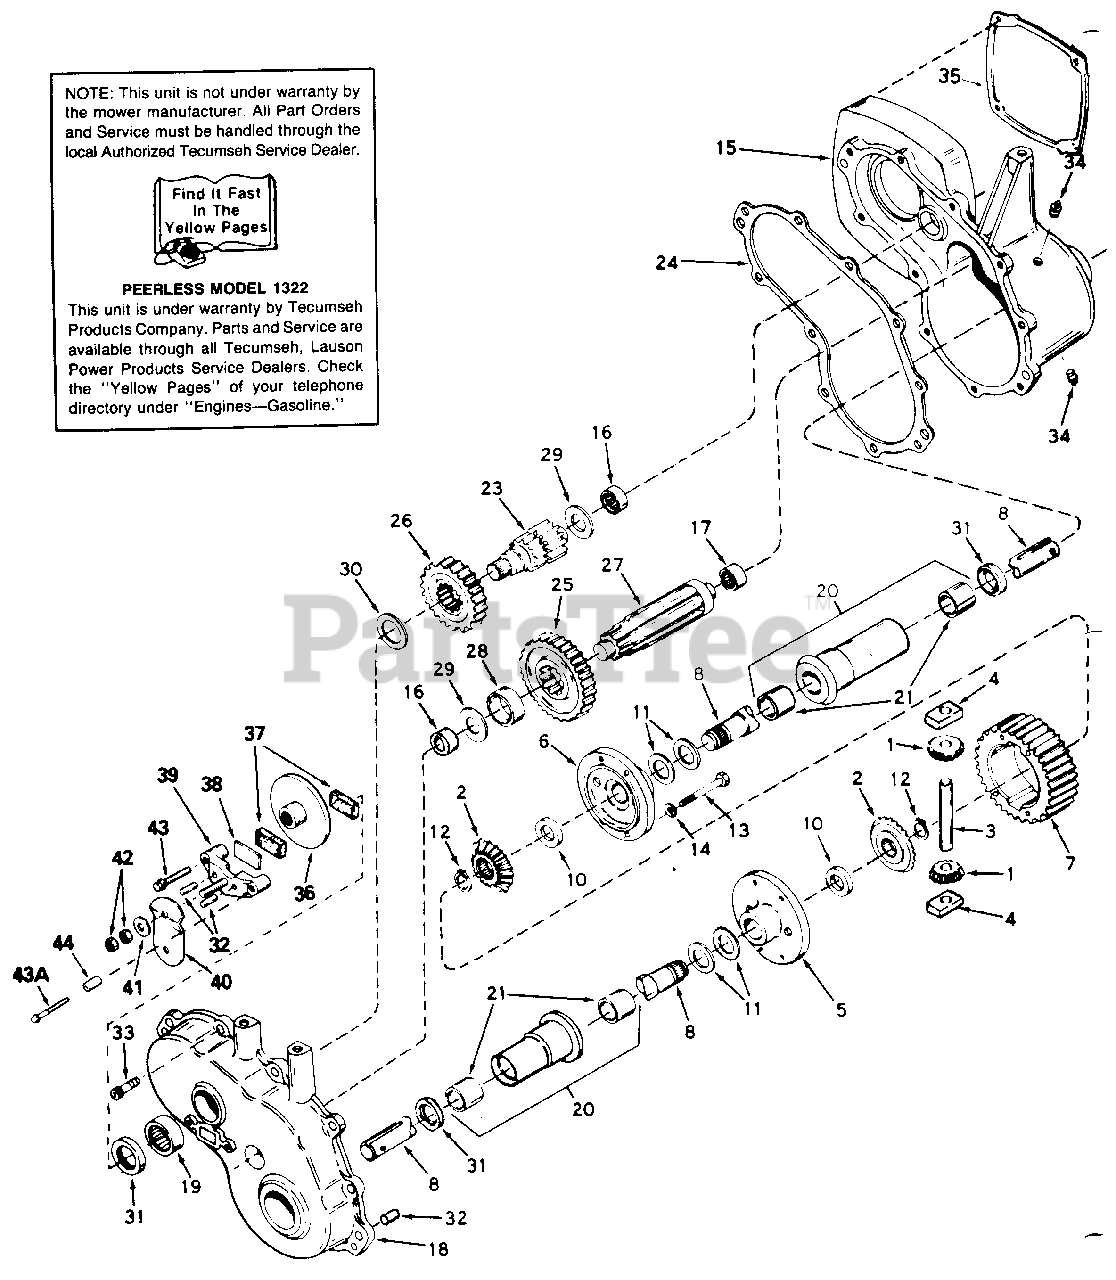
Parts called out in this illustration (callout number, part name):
1	Pinion, Bevel
2	Gear, Bevel
3	Pin, Drive
4	Block, Drive
5	Carrier, Differential
6	Carrier, Differential
7	Gear, Ring
8	Axle (16-1/64" Long)
10	Washer
11	Washer, Thrust
12	Ring, Snap
13	Screw, Hex Hd. 1/4-20 x 21/4
14	Lock Washer, 1/4"
15	Case Ass'y.
16	Bearing, Needle
17	Bearing, Needle
18	Cover Ass'y.
19	Bearing, Needle
20	Housing Ass'y., Axle
21	Bushing
23	Shaft, Brake
24	Gasket, Case to Cover
25	Gear, Output
26	Gear, Idler
27	Shaft, Output
28	Spacer
29	Washer
30	Washer
31	Seal, Oil
32	Pin, Dowel
33	Screw, Hex Hd., Self-Tapping, 1/4-20 x 1
34	Plug, Pipe
35	Gasket
36	Disc, Brake
37	Pad, Brake
38	Plate, Brake Pad
39	Holder, Brake Pad
40	Lever, Brake
41	Washer, Flat
42	Lock Nut 5/16-24
43	Screw, Hex Hd., Self-Tapping, 1/4-20 x 11/4
43A	Screw, Hex Hd., Self-Tapping, 1/4-20 x 21/4
44	Spacer
